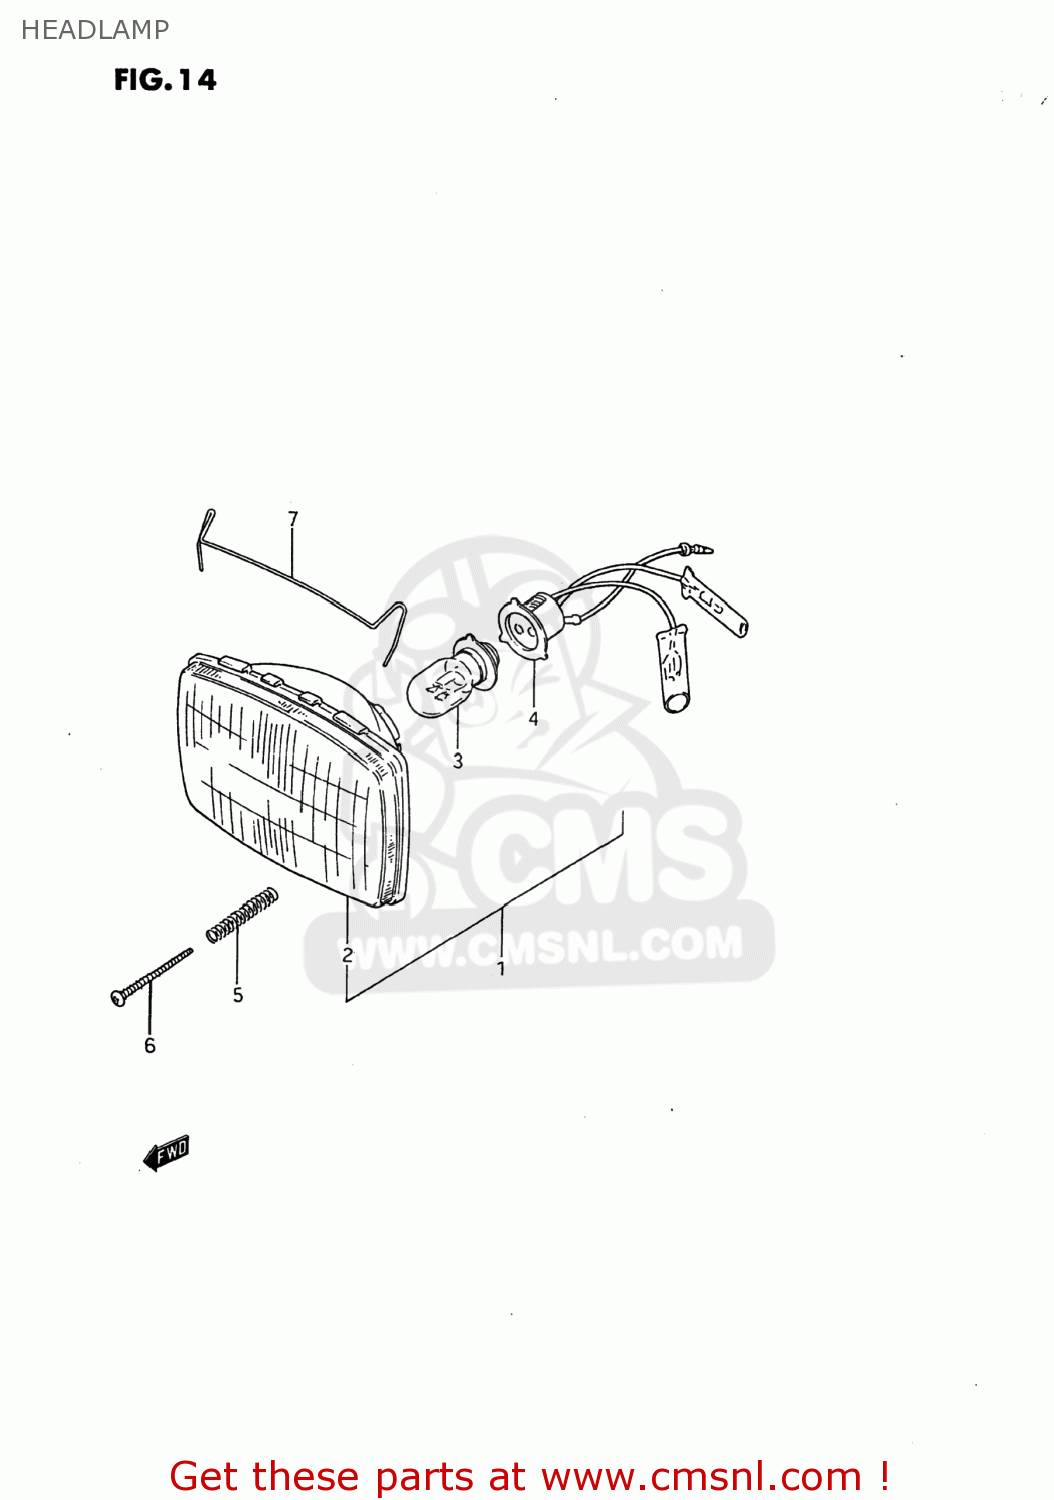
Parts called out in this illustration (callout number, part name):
1	HEADLAMP ASSEMBLY
2	LAMP UNIT
3	BULB(6V15/15W/STANLEY,A3598HA)
4	SOCKET,HEADLAMP
5	SPRING,HEAD LAMP ADJUSTER
6	SCREW
7	SPRING,SUPPORT
